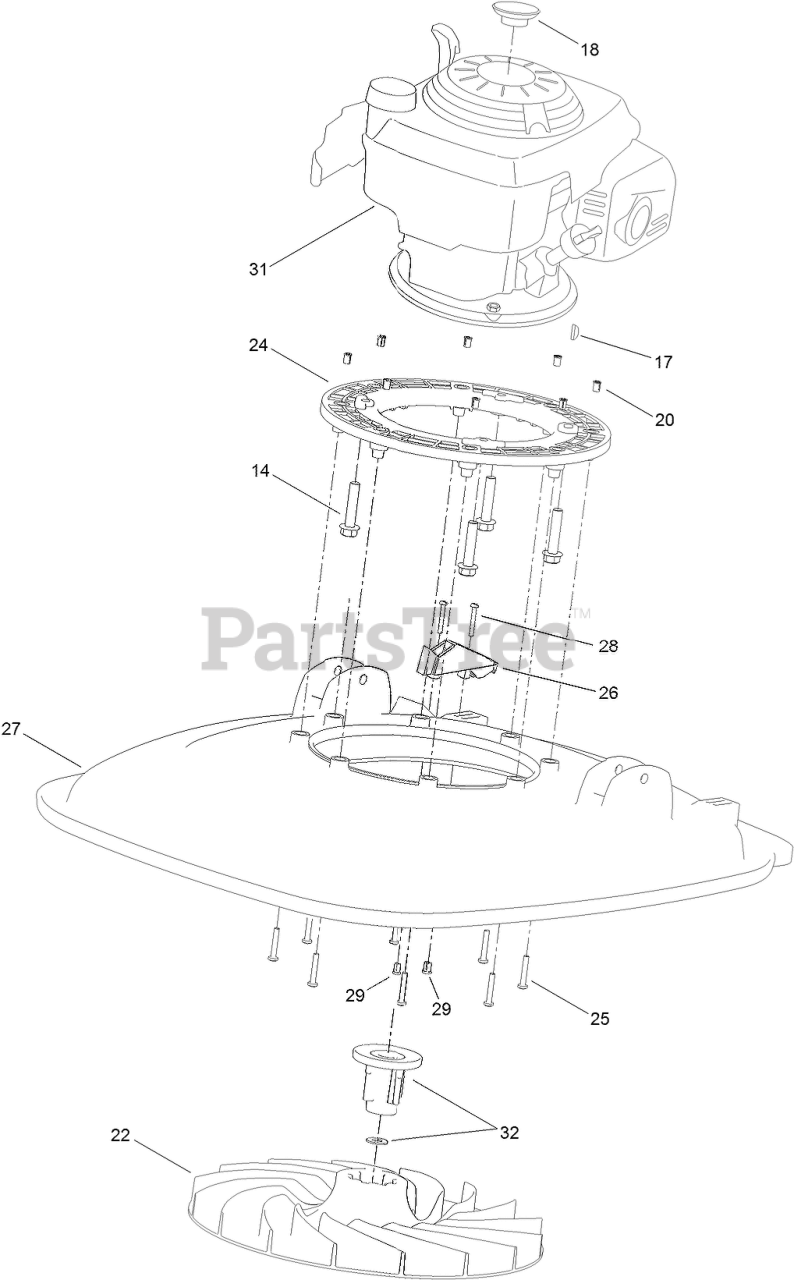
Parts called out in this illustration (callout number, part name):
14	SCREW-TAPTITE
17	KEY-WOODRUFF
18	PROTECTOR-SEAL, OIL
20	INSERT-BRASS
22	IMPELLER
24	FRAME-MOUNTING, ENGINE
25	SET-SCREW
26	BRACKET
27	DECK
28	SCREW
29	INSERT
31	Engine-Honda
32	DRIVE AND SPACER ASM
